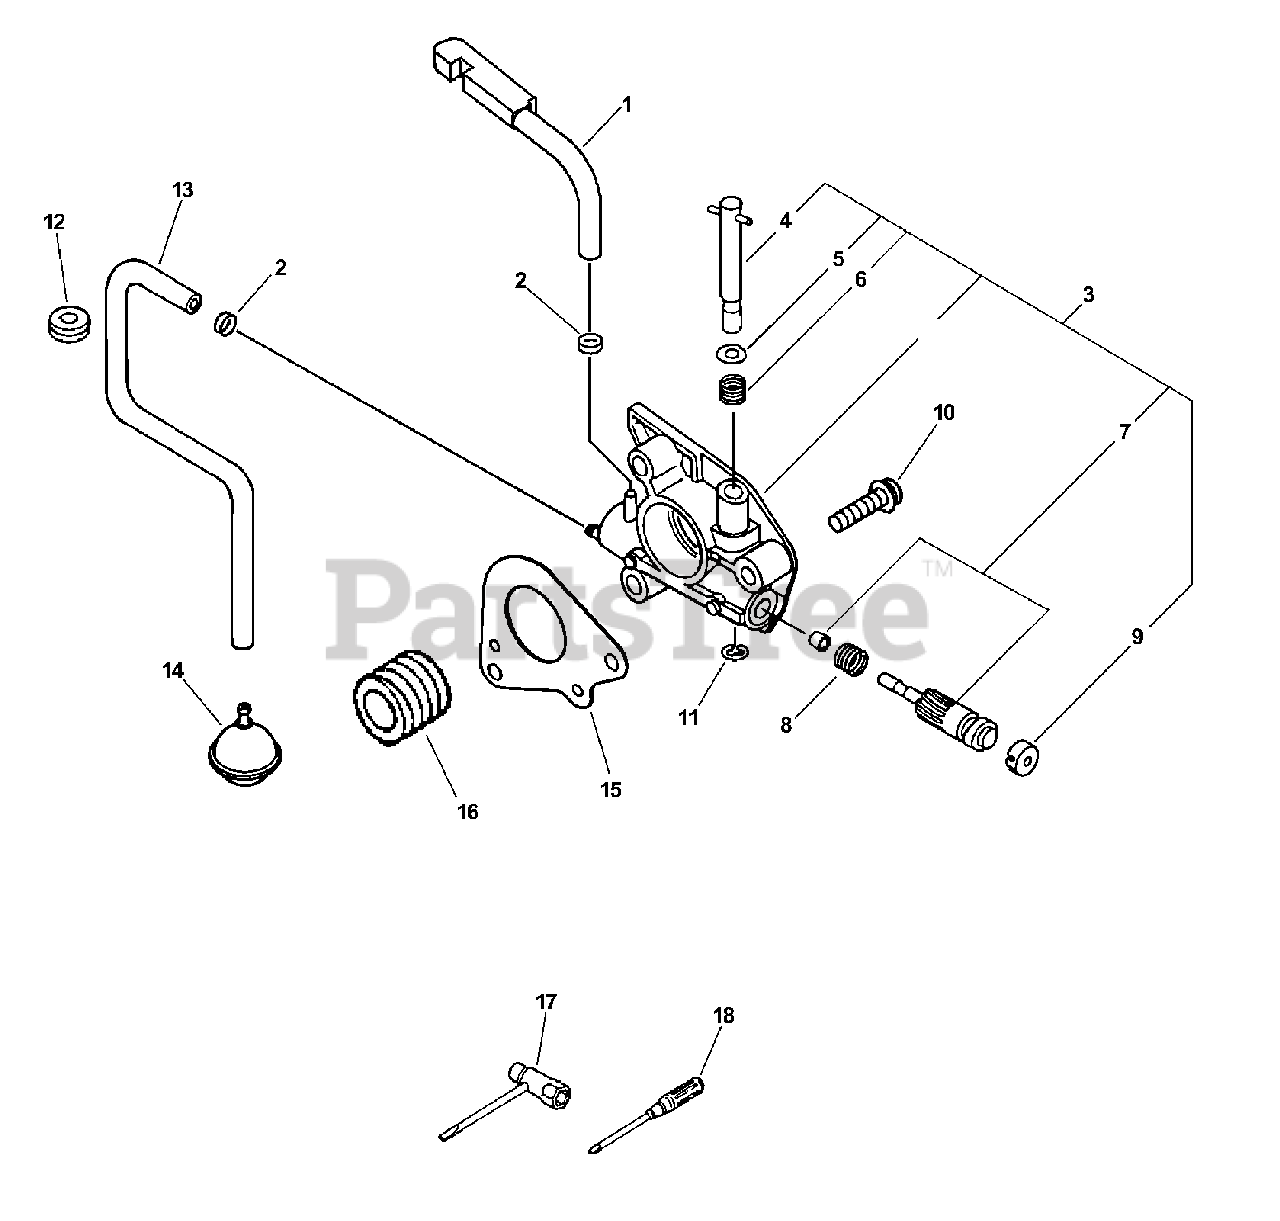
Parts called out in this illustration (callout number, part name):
1	PIPE - OIL
2	CLIP - 6.5
3	AUTO-OILER ASSY
4	NEEDLE, ADJUST
7	PLUNGER ASSY
8	SPRING, PLUNGER
9	CAP, OIL PUMP
10	SCREW - 4X16
11	RING, RETAINING
13	PIPE - OIL
14	FILTER, OIL
15	SEAL, DUST
16	GEAR - WORM
17	T-WRENCH - 13X19mm
18	SCREWDRIVER
